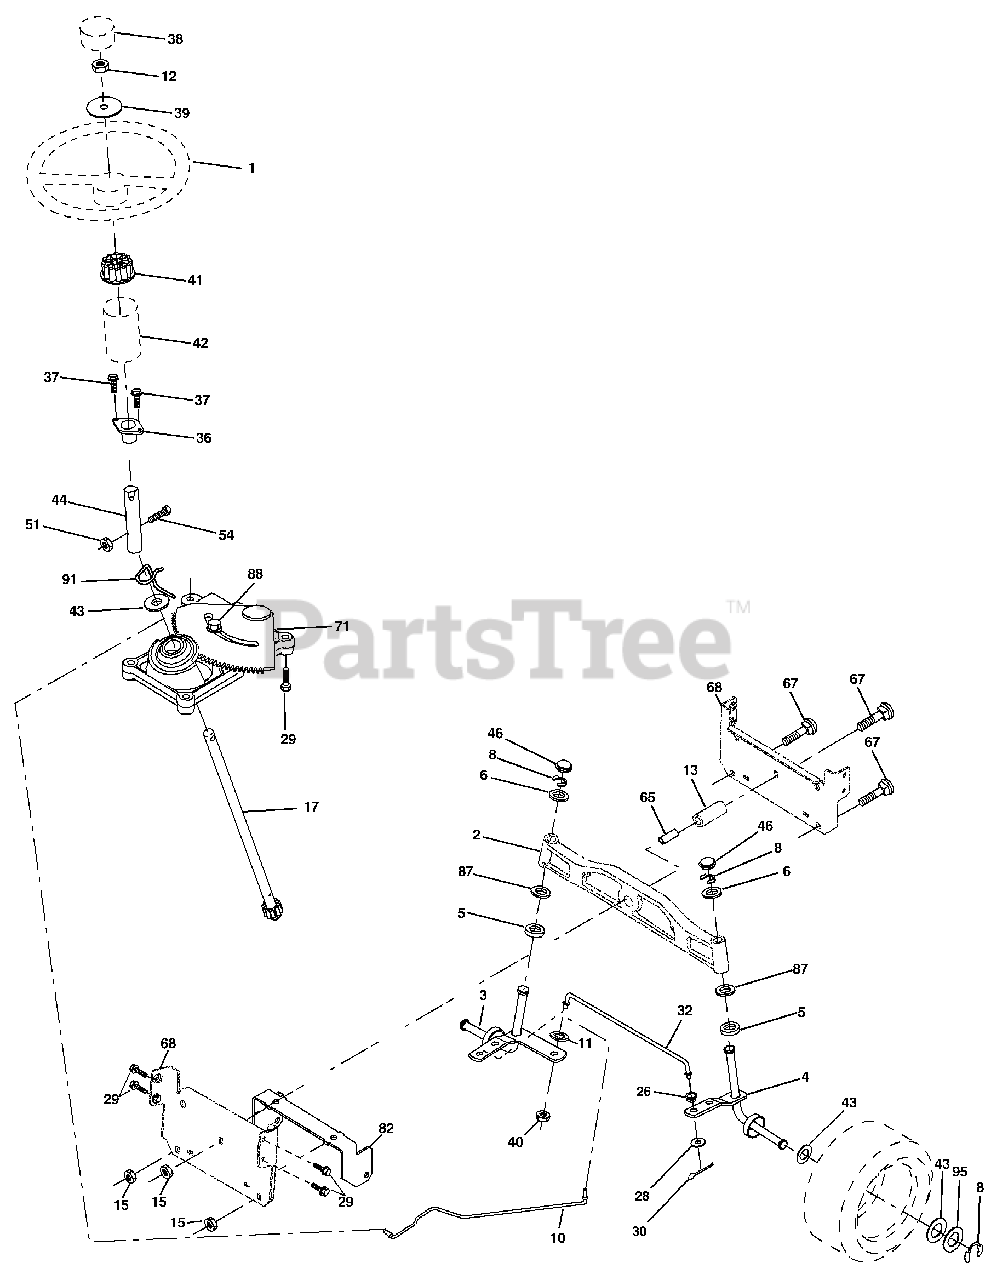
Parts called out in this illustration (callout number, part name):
1	Wheel Steering
2	Axle Asm Cast Iron LT
3	Spindle Asm LH
4	Spindle Asm RH
5	Bearing Race Thrust Harden
6	Washer 25/32 x 1-5/8 x 16 Ga.
8	Ring Klip #t5304-75
10	Link Drag
11	Washer Lock Hvy Hlcl Spr 3/8
12	Nut Hex Jam Toplock 1/2-20 unf
13	Spacer Brg. Axle Front
15	Nut Hex Flange Lock
17	Shaft Asm. Steering
26	Bushing Link Drag
28	Washer 13/32 x 7/8 x 16 Ga.
29	Screw 3/8-16 x .75
30	Pin Cotter 1/8 x 3/4
32	Rod Tie
36	Bushing Strg
37	Screw
38	Insert Cap Strg Wh Au
39	Washer
40	Nut Crownlock 3/8-24
41	Adaptor Wheel Strg
42	Boot Steering Dash
43	Washer 25/32 x 1 1/4 x 16 Ga.
44	Extension Steering Shaft
46	Cap Spindle Fr Top Blk
51	Nut Crownlock 1/4-28
54	Bolt Hex 1/4-28 Unf x 1-1/4 Gr. 8
65	Brace Axle
67	Bolt Rdhd Sq 3/8-16 unc x 2-1/4
68	Axle, Brace
71	Steering Asm.
82	Bracket Susp. Chassis Front
87	Washer Flat .781 x 1-1/2 x 14
88	Bolt Shoulder 7/16-20 unc
91	Clip Steering
95	Washer Harden .793 x 1.637 x 060
